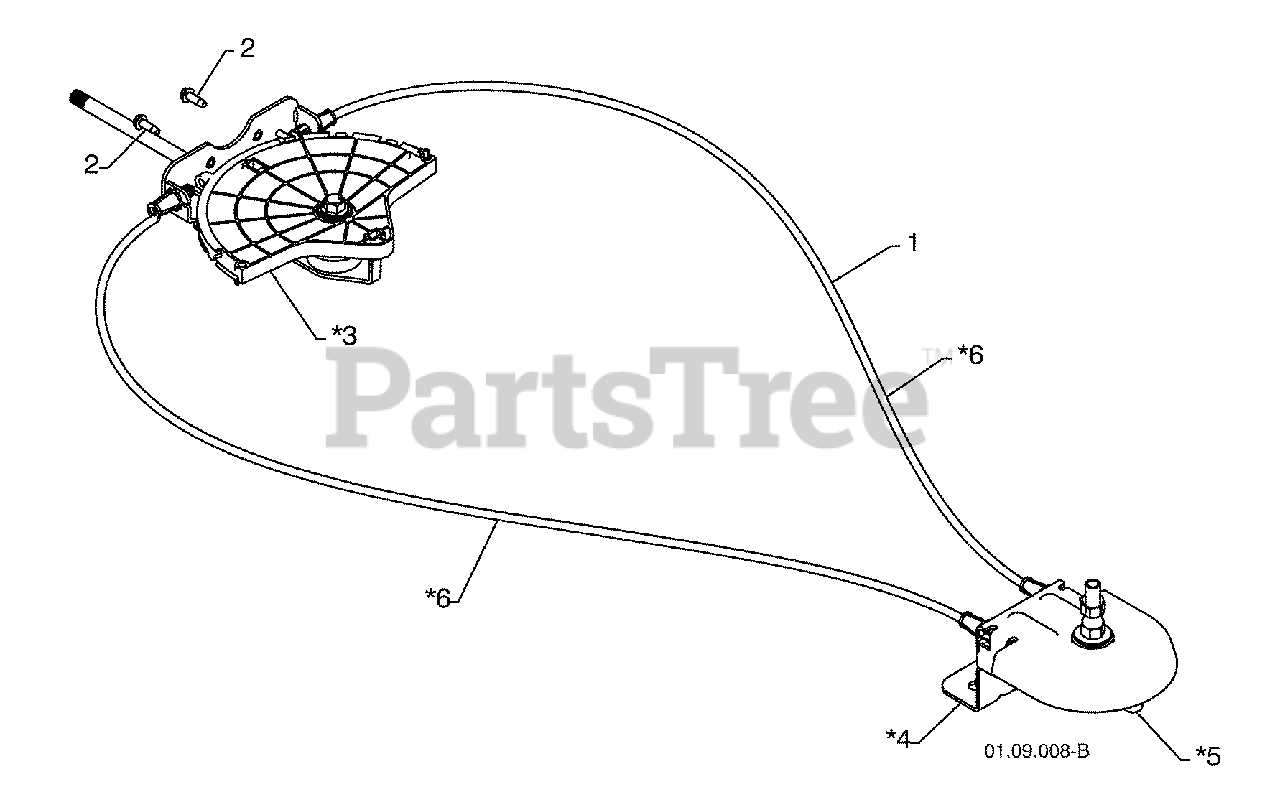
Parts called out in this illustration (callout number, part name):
1	LEVER/CABLE ROTATOR ASSEMBLY GRAY
2	SCREW 10-24 X .625
3	ROTATOR HEAD
4	ROTATOR PIVOT BRACKET
5	PULLEY PIVOT
6	CABLE ASSEMBLY GRAY
